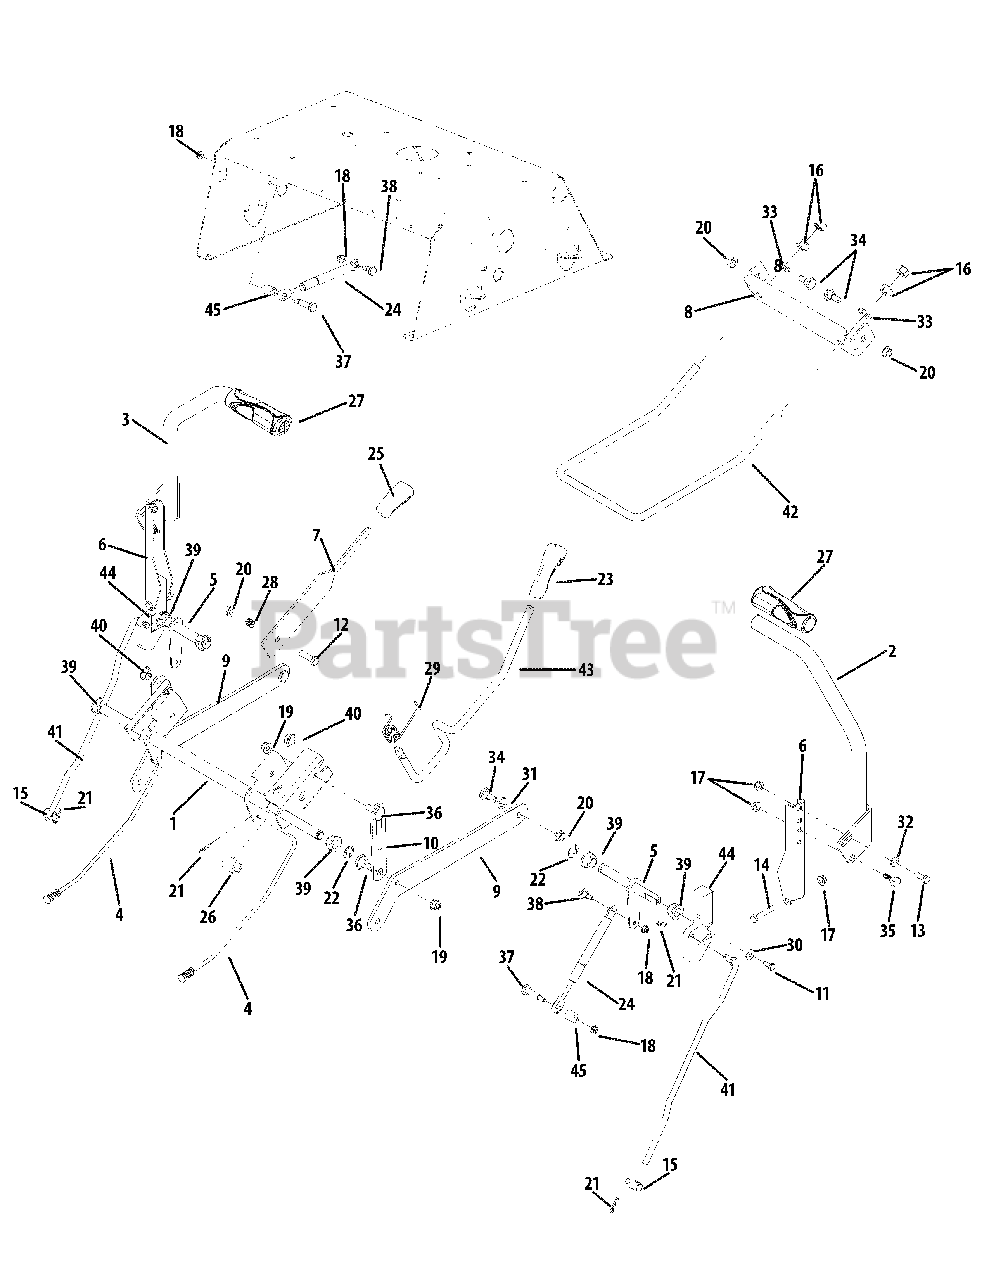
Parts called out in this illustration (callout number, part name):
5	Control Shaft
6	Lapbar Pivot Bracket
11	Hex Lock Screw, 1/4-20 x .62
12	Hex Cap Screw,3/8-16 x 1.25
13	Hex Cap Screw, 5/16-18 x .75
14	Hex Cap Screw, 5/16-18 x 1.75
15	Ferrule, 3/8 -24 x .375
16	Hex Nut, 1/2-13
17	Hex Flange Insert Lock Nut, 5/16-18
18	Hex Flange Insert Lock Nut, 1/4-20
19	Hex Flange Insert Lock Nut, 3/8-16
20	Hex Flange Lock Nut, 3/8 -16
21	Cotter Pin
22	E-Ring, .625 Dia.
23	Handle Grip
24	Damper Cylinder
25	Handle Grip
26	Spacer, .62 x 1.0
27	Hand Grip
28	Compression Spring
29	Spring, Torsion RZT
30	Bell Washer, .265 x .75 x .062
31	Flat Washer, .51 x 1.0 x .06
32	Flat Washer, .344 x .688 x .065
33	Flat Washer, .531 x 1.062 x .134
34	Shoulder Screw, .498 x .340 x 3/8-16
35	Shoulder Screw, .437 x .268 x 5/16-18
36	Shoulder Screw, .5 x .434 x 3/8-16
37	Shoulder Screw, .374 x 1.16 x 1/4-20
38	Shoulder Screw, .375 x .38 x 1/4-20
39	Hex Flange Bearing
40	Flange Bearing, .626 x .938 x .344
41	Lapbar Control Rod
42	Deck Front Hanger Rod
43	Deck Lift Handle Rod
45	Spacer, .385 x .630 x .75
